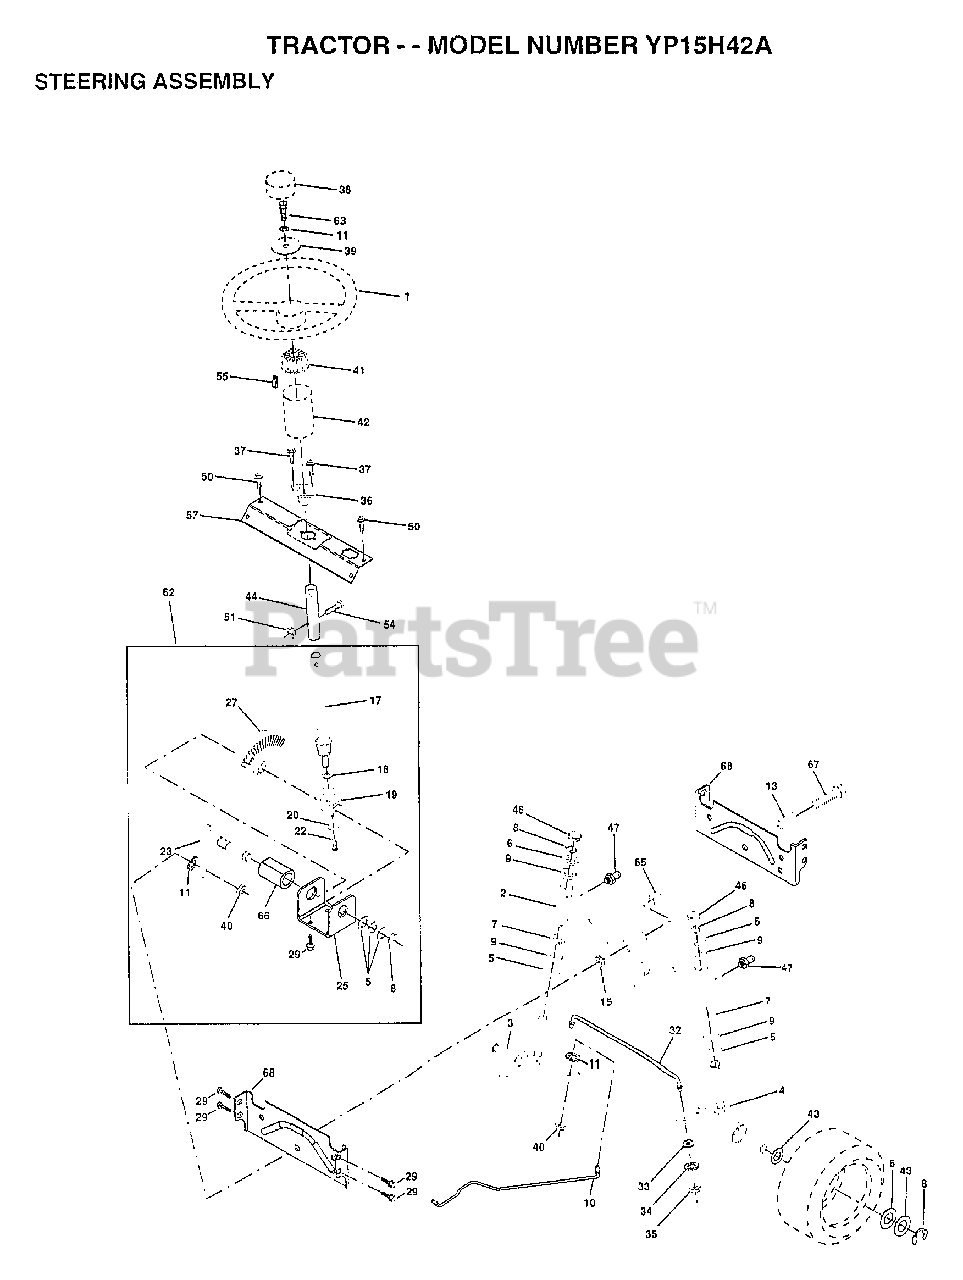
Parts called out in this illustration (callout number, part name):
2	AXLE ASM
3	SPINDLE.ASM.LH
4	"SPINDLE ASM,RH"
5	WASHER .T
6	WASHER
7	WASHER
8	RING
9	COL. SRTG. BEAR.
10	DRAGLINK-STAMPED
11	LOCKWASHER
13	BEARING AXLE
15	"NUT-LOC,FLANGE LT"
17	SHAFT ASM STEERIN
18	THRUST WASHER
19	SUPPORT.SHAFT
22	SCREW HEX SOC1/4-
25	BRKT-STEERING
27	GEAR SECTOR
29	SCREW
32	ROD.TIE.19.75
33	WASHER 11/32 X 3/4 /16 GA
34	LOCKWASHER
35	NUT.LOCK.5/16-24
36	BUSHING.STR.623
37	"SCREW-TT,10-32 FL"
38	"INSERT,STR WHEEL"
39	WASHER T
40	GRIPCO NUT
41	ADAPTER LT
42	BOOT SHAFT STEER
43	WASHER
44	SHAFT EXT STEERIN
46	CAP
47	ZERK M
50	SCREW HEX CRT
51	NUT
54	BOLT
55	CLIP TINNERMAN
57	SUPPORT SHAFT STR
62	KIT STEERING ASM
63	BOLT
65	SPACER AXLE
66	"BEARING-ARM,PITMA"
67	BOLT
68	BRACE AXLE
